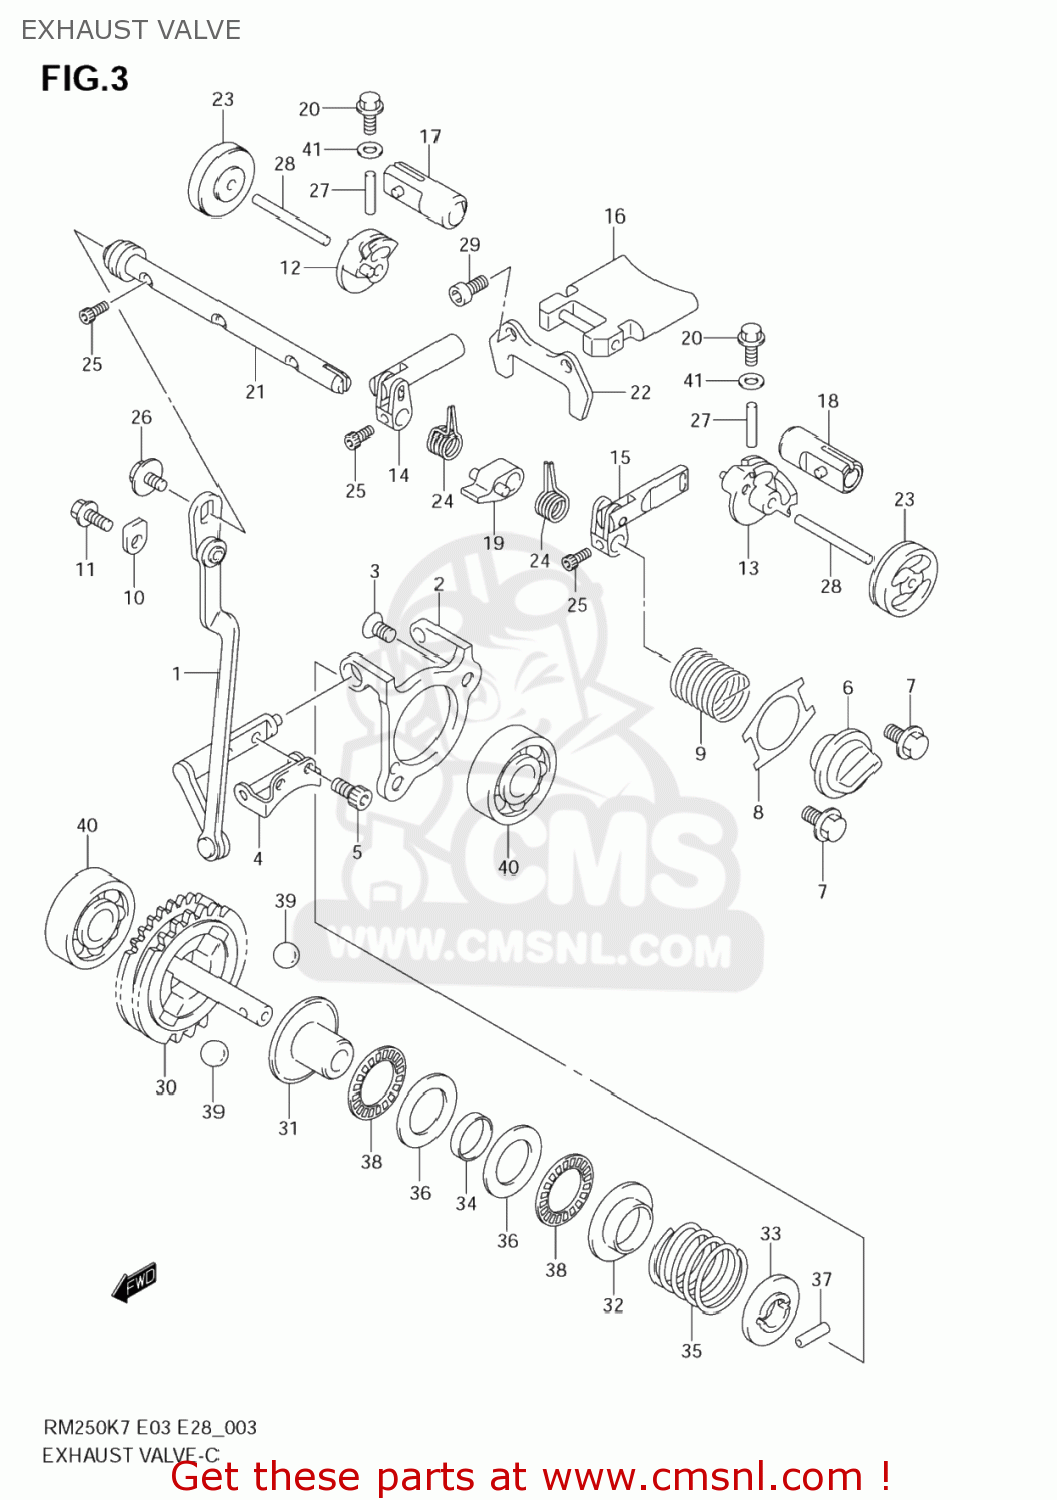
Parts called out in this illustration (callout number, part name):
1	ACTUATOR ASSY,EXHAUST VALVE
2	BASE,ACTUATOR
3	SCREW(5X10)
4	ARM,ACTUATOR
5	BOLT(4X8)
6	CAP,EXHAUST VALVE SHAFT SPRING
7	BOLT(5X10)
8	GASKET,EXHAUST VLV SPRING CAP (NAS)
9	SPRING,CYL COVER NO.2 SHAFT
10	RETAINER
11	BOLT(6X10)
12	CAM,EXHAUST SIDE VALVE,R
13	CAM,EXHAUST SIDE VALVE,L
14	ROD ASSY,EXH SIDE VALVE CAM,R
15	ROD ASSY,EXH SIDE VALVE CAM,L
16	VALVE ASSY,EXHAUST MAIN
17	VALVE ASSY,EXHAUST SIDE,R
18	VALVE ASSY,EXHAUST SIDE,L
19	ARM ASSY,EXH MAIN VALVE
20	CAP,EXHAUST SIDE VLV STOP PIN
21	SHAFT,EXHAUST VALVE
22	PLATE,EXHAUST MAIN VALVE
23	SPACER,EXHAUST SIDE VALVE
24	SPRING,EXHAUST MAIN VALVE ARM
25	BOLT(4X8)
26	BOLT(5X12)
27	ROLLER(4X23.8)
28	PIN(4X39.8)
29	BOLT
30	GOVERNOR,DRIVE
31	GOVERNOR,DRIVEN
32	STOPPER,GOVERNOR SPRING NO.1
33	STOPPER,GOVERNOR SPRING NO.2
34	SPACER,GOVERNOR
35	SPRING,GOVERNOR
36	SHIM(15X28X1)
37	ROLLER(3X12.5)
38	BEARING(15X28X2)
39	BALL
40	BEARING(8X22X7)
41	GASKET(8.2X14X1).6 (NAS)
